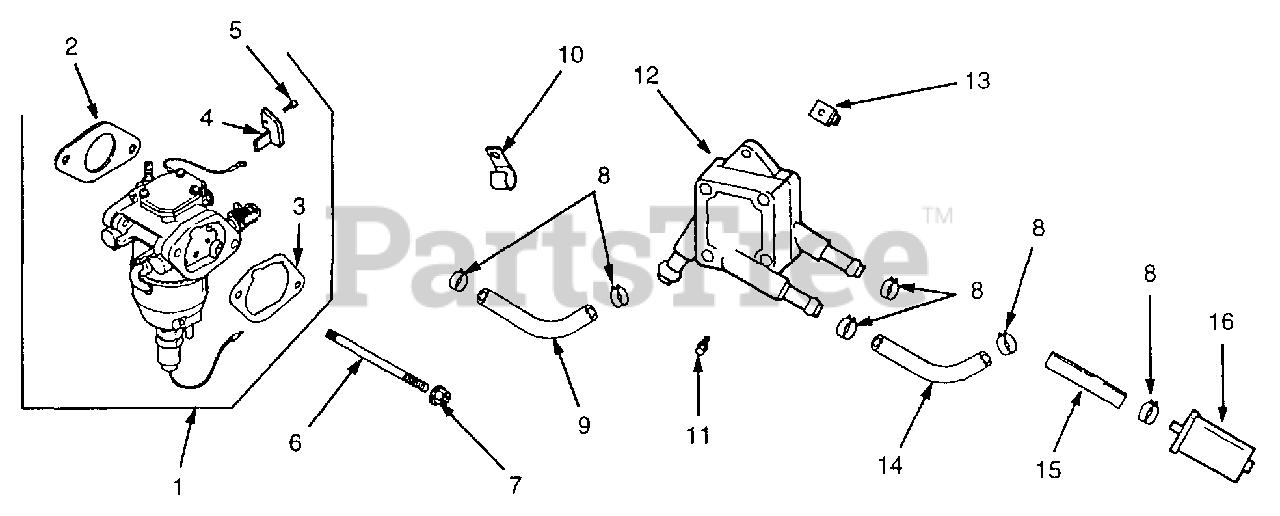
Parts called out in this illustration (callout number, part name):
1	Kit, Carburetor w/Gaskets
2	Gasket, Carburetor
3	Gasket, Air Cleaner Base
4	Bracket, Throttle Stop
5	Screw, Throttle Stop
6	Stud, M6 x 1.0 x 128
7	Nut, Hex Flange, M6 x 1.0
8	Clamp, Hose
9	Fuel Line 10 5"
10	Clip, Cable
11	Screw, Hex Cap, M6 x 1.7 x 18
12	Pump, Pulse Fuel
13	Nut, Plastic
14	Fuel Line 11.5"
15	Fuel Line 3.5"
16	Filter, Fuel
